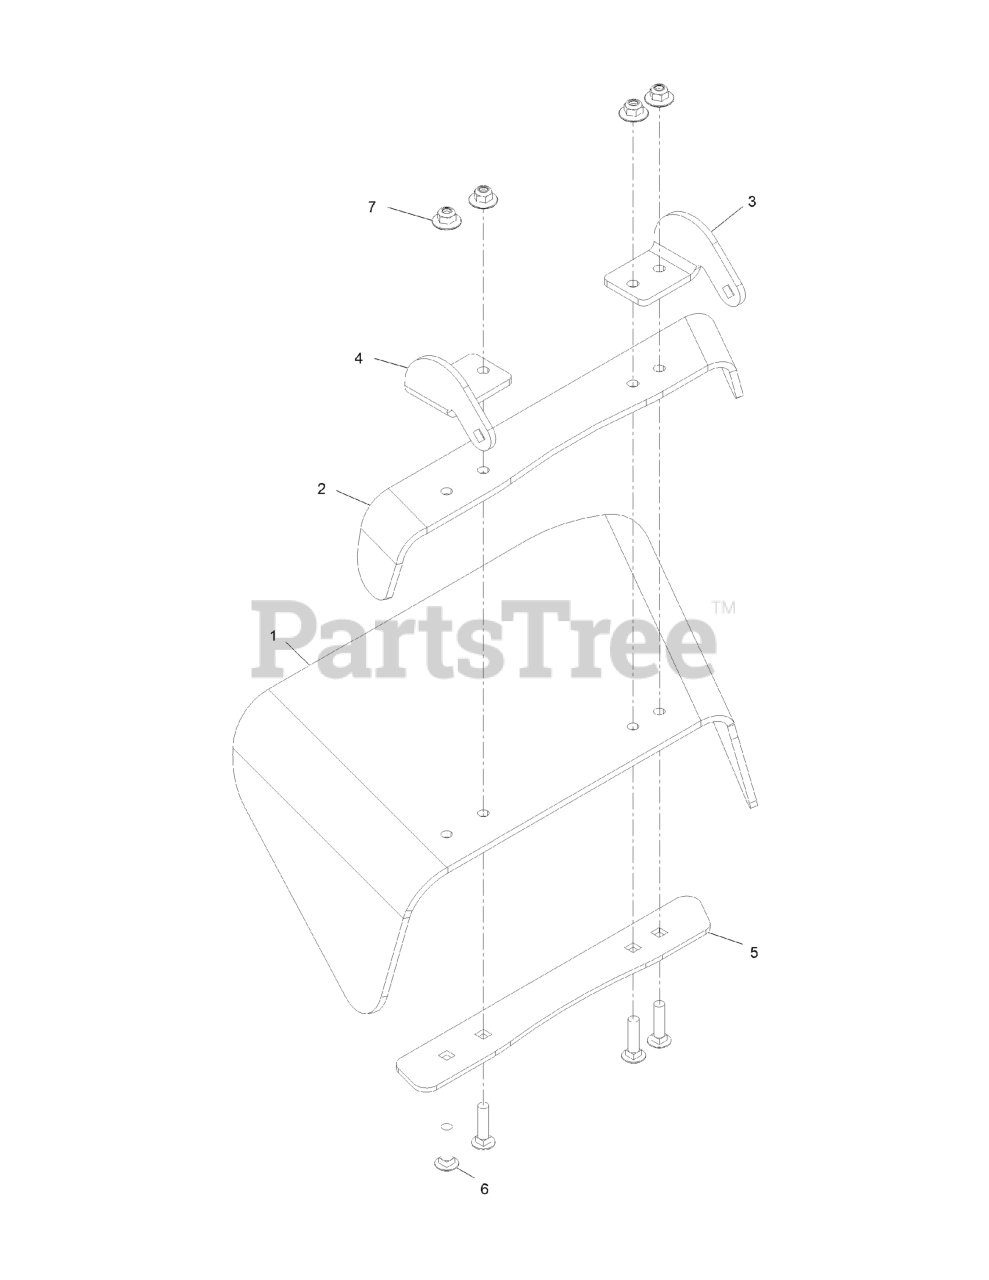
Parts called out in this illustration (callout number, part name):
1	DEFLECTOR-RUBBER
2	BRACKET-TOP DEFLECTOR
3	BRACKET-DEFLECTOR
4	BRACKET-DEFLECTOR
5	STRAP-BOTTOM DEFLECTOR
6	SCREW-CARR
7	Nut-Nyloc 3/8-16 Flg
